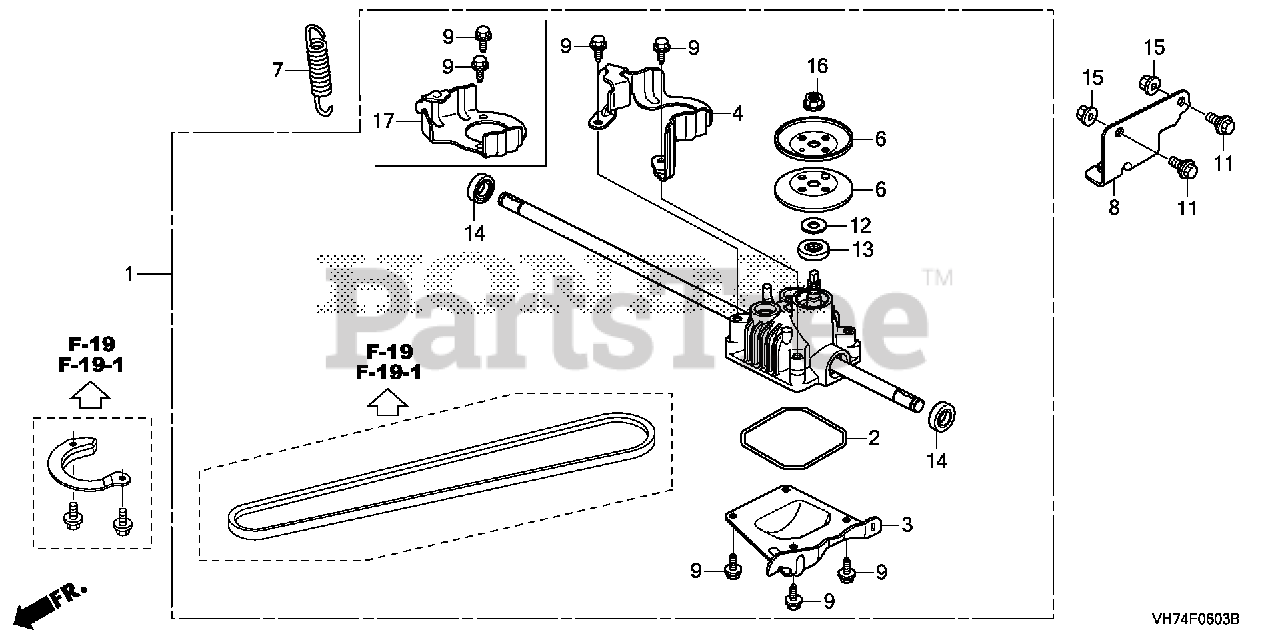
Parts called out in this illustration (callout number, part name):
1	TRANSMISSION ASSY.
2	O-RING, CASE
3	COVER, REDUCTION
4	GUIDE, BELT
6	FACE, DRIVEN
7	SPRING, WHEEL TENSION
8	BRACKET, CABLE MOUNT
9	BOLT, FLANGE (6X12) (CT200)
11	BOLT, CABLE MOUNT
12	WASHER (10X24)
13	OIL SEAL (12.7X28.6X6.4)
14	OIL SEAL (12.7X22.2X6.4)
15	NUT, FLANGE (8MM)
16	NUT, FLANGE (10MM)
17	GUIDE, BELT
